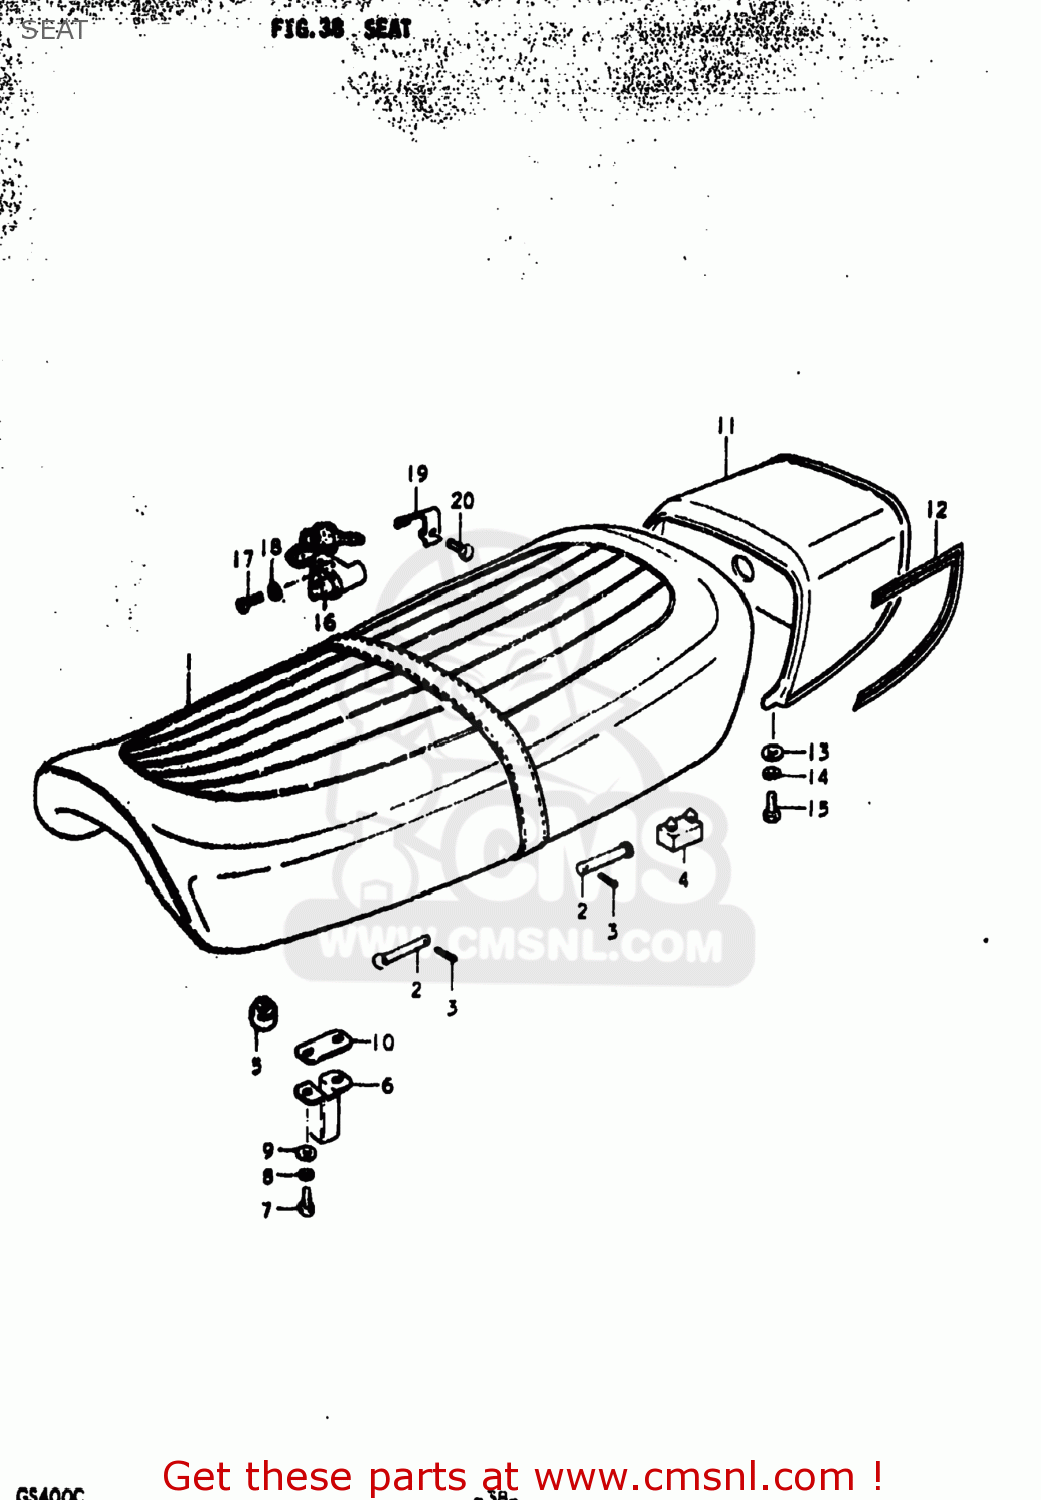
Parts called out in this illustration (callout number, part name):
1	SEAT ASSEMBLY
2	PIN
3	PIN
4	CUSHION
5	CUSHION(11.5X22X20)
6	STRIKER,SEAT LOCK
7	BOLT
8	LOCK WASHER
9	WASHER
10	SHIM,SEAT LOCK STRIKER
11	COVER,SEAT TAIL
13	WASHER
14	LOCK WASHER
15	BOLT, UPPER
16	LOCK ASSEMBLY,SEAT
17	SCREW
18	LOCK WASHER
19	SPRING,HELMET HOLDER
20	BOLT 5X16
